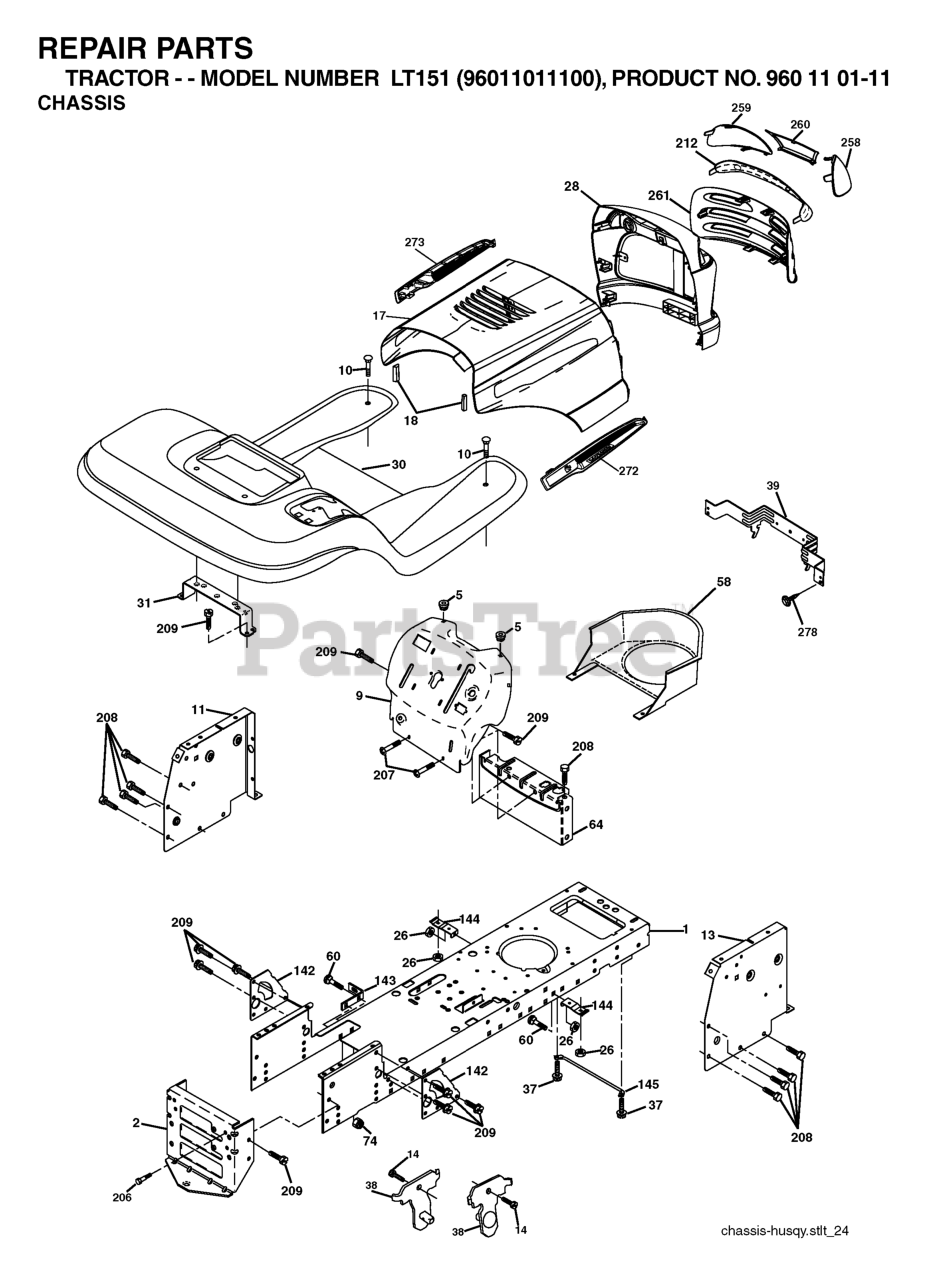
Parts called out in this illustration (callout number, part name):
1	CHASSIS STAMPING
2	DRAWBAR, 12GA
5	BUMPER.RUBBER.HOOD
9	FENDER.STL.W/O CUPHLDR.ROS.422
10	BOLT D
11	PANEL.DASH.LH.LTX
13	PANEL DASH RH
17	VENT.HOOD.LASER.III
18	BUMPER.HOOD.LARGE.1.75"
26	NUT
31	BRACKET.SUPPORT.FENDER
37	Screw 5/16-18 x 1/2 Hex, Self Tapping 5/16-18 x 1/2
38	BRACKET.ASM.PIVOT.MOWER.REAR
39	BRACKET PIVOT LASER
60	Bolt - Rd. Hd. Sq. Neckiage 3/8 16 x 3/4
64	DASH LOWER
142	PLATE REINFORCEMENT
143	BRACKET, SWAYBAR CHASSIS
144	BRKT, FOOT REST
145	ROD PIVOT CHASSIS/HOOD
206	SHOULDER BOLT 5/16-18TT
207	SCREW, 5/16-18 X 1/2
208	SCREW 3/8-16X1/2
209	SCREW, 3/8-16X3/4
212	INSERT.LENS.REFLECTIVE
258	LENS LH
259	LENS LH
260	COVER.LENS.HUSQ.LASER
272	VENT.HOOD.LASER.
273	VENT.HOOD.LASER.
278	SCREW
